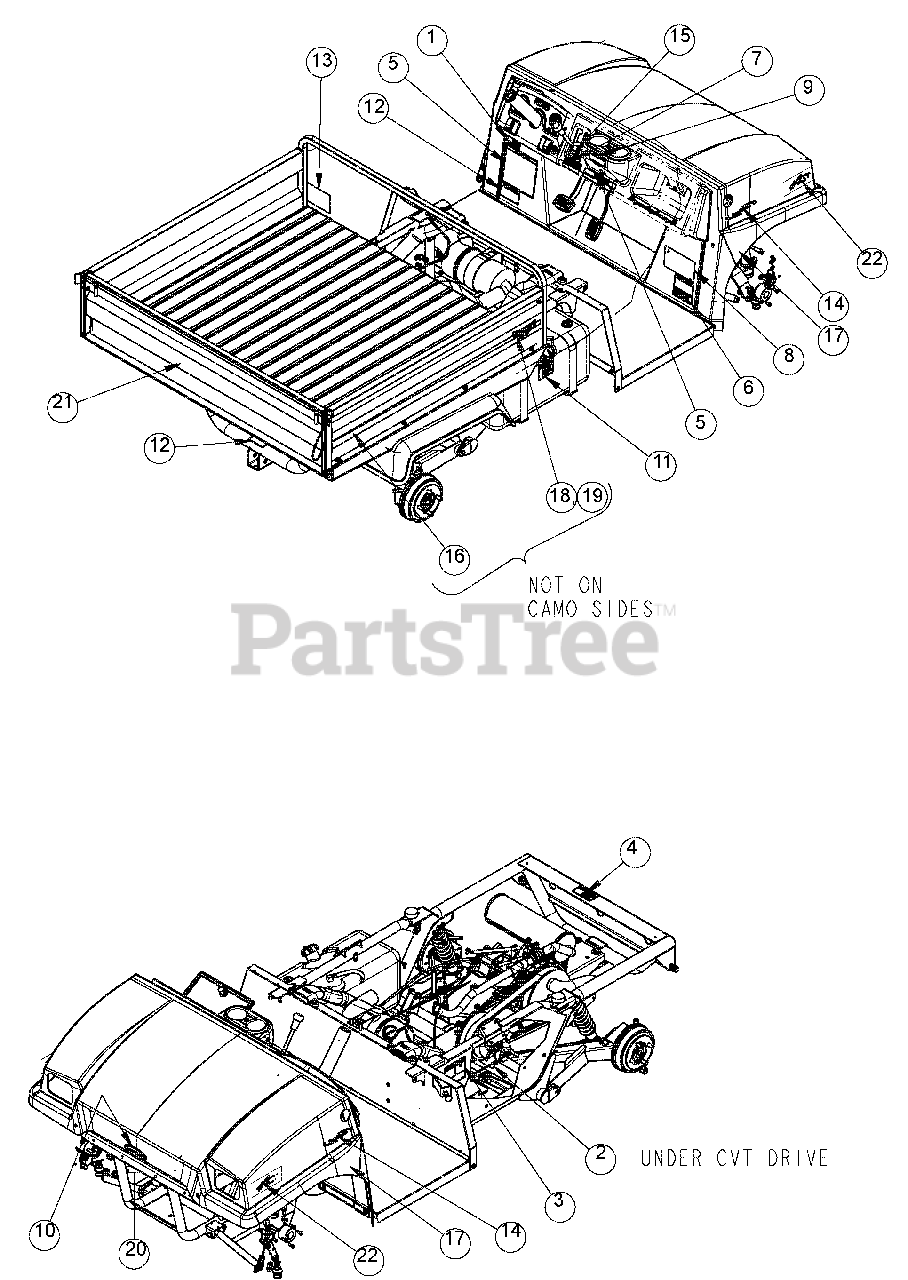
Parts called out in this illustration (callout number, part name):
1	DECAL FLAG
2	DECAL DANGER PD GUARD MISS SML
3	DECAL DANGER BATTERY
4	DECAL DANGER HOT
5	DECAL WARNING GNRAL UTLTY VHCL
6	DECAL WARNING ROLLOVER HAZARD
7	DECAL CAUTION STOP ENGINE
8	DECAL WARNING IMPROPER USE
9	DECAL CAUTION PWR SRC MAX 12V
10	DECAL WARNING ENG. COOL B4 GAS
11	DECAL WARNING VEHICLE ROLLOVER
12	DECAL WARNING (GVW)LOAD 4400ST
13	DECAL TRAILER TOWING NT/ST
14	DECAL WARNING PINCH PT/CRUSH
15	DASH SHIFTER DECAL
16	DECAL, TREKER RED STRIPE Not on Camo Unit
17	DECAL, 4 X 4
18	DECAL, GRAVELY TREKER STRIP LH
19	DECAL, GRAVELY TREKER STRIP RH
20	DECAL, GRAVELY TREKER LOGO FRONT
21	DECAL, GRAVELY LOGO
22	DECAL, GRAVELY TREKER LOGO LH
